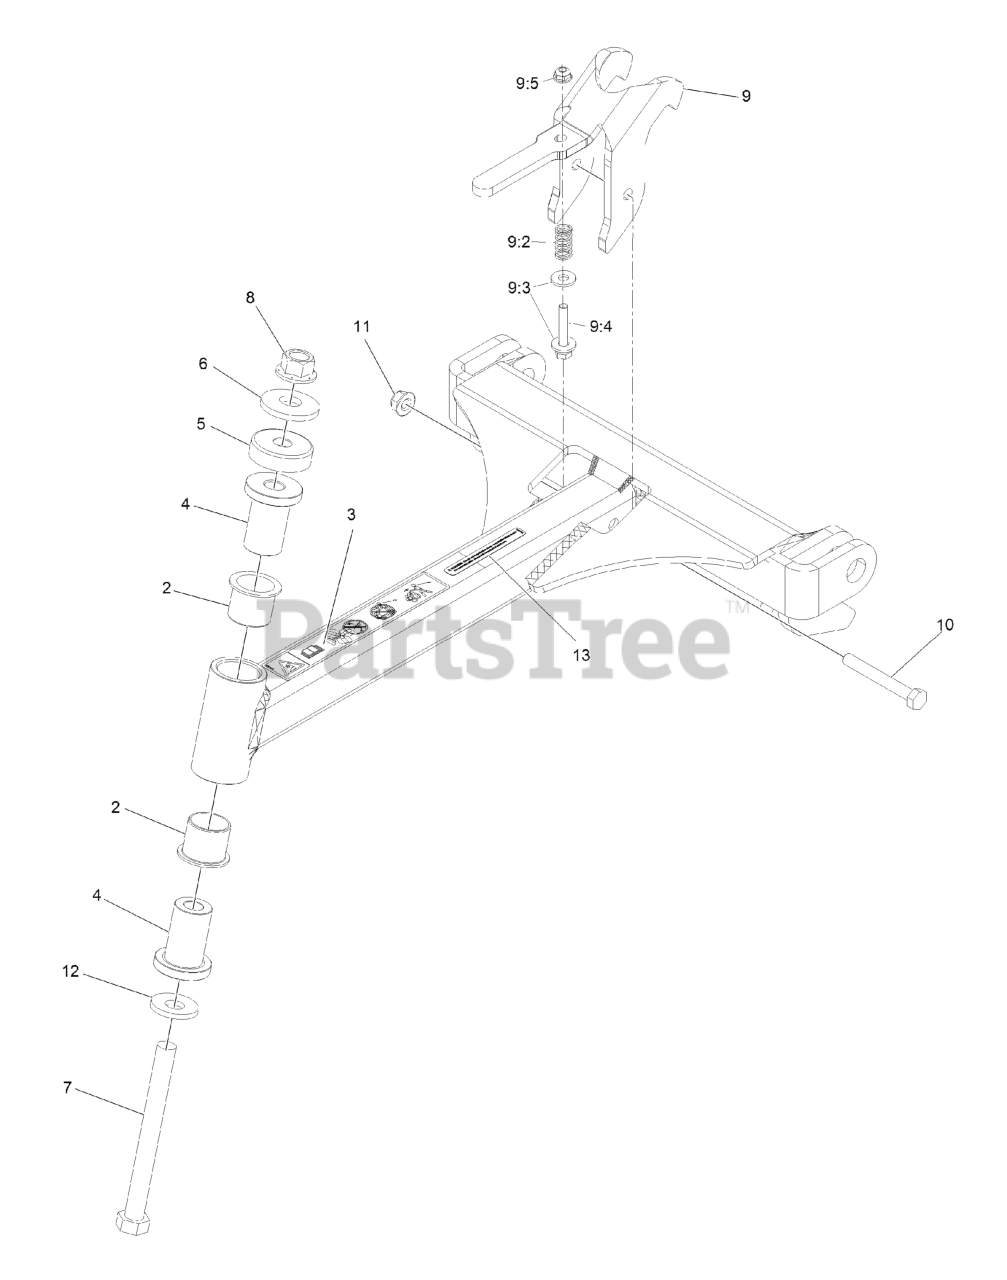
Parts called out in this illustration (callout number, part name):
2	BUSHING-PIVOT
3	DECAL-SULKY HAZARD
4	SPACER, PIVOT
5	COVER, DUST
6	WASHER-BELLEVILLE
7	SCREW-HH
8	Nut-Lock 1/2-13
9	TRANSPORT LATCH ASM
9:2	SPRING, COMPRESSION
9:3	WASHER-FLAT
9:4	SCREW-HH
10	SCREW-HH
11	NUT-HF, NI
12	WASHER-SPRING
13	DECAL-WARNING
